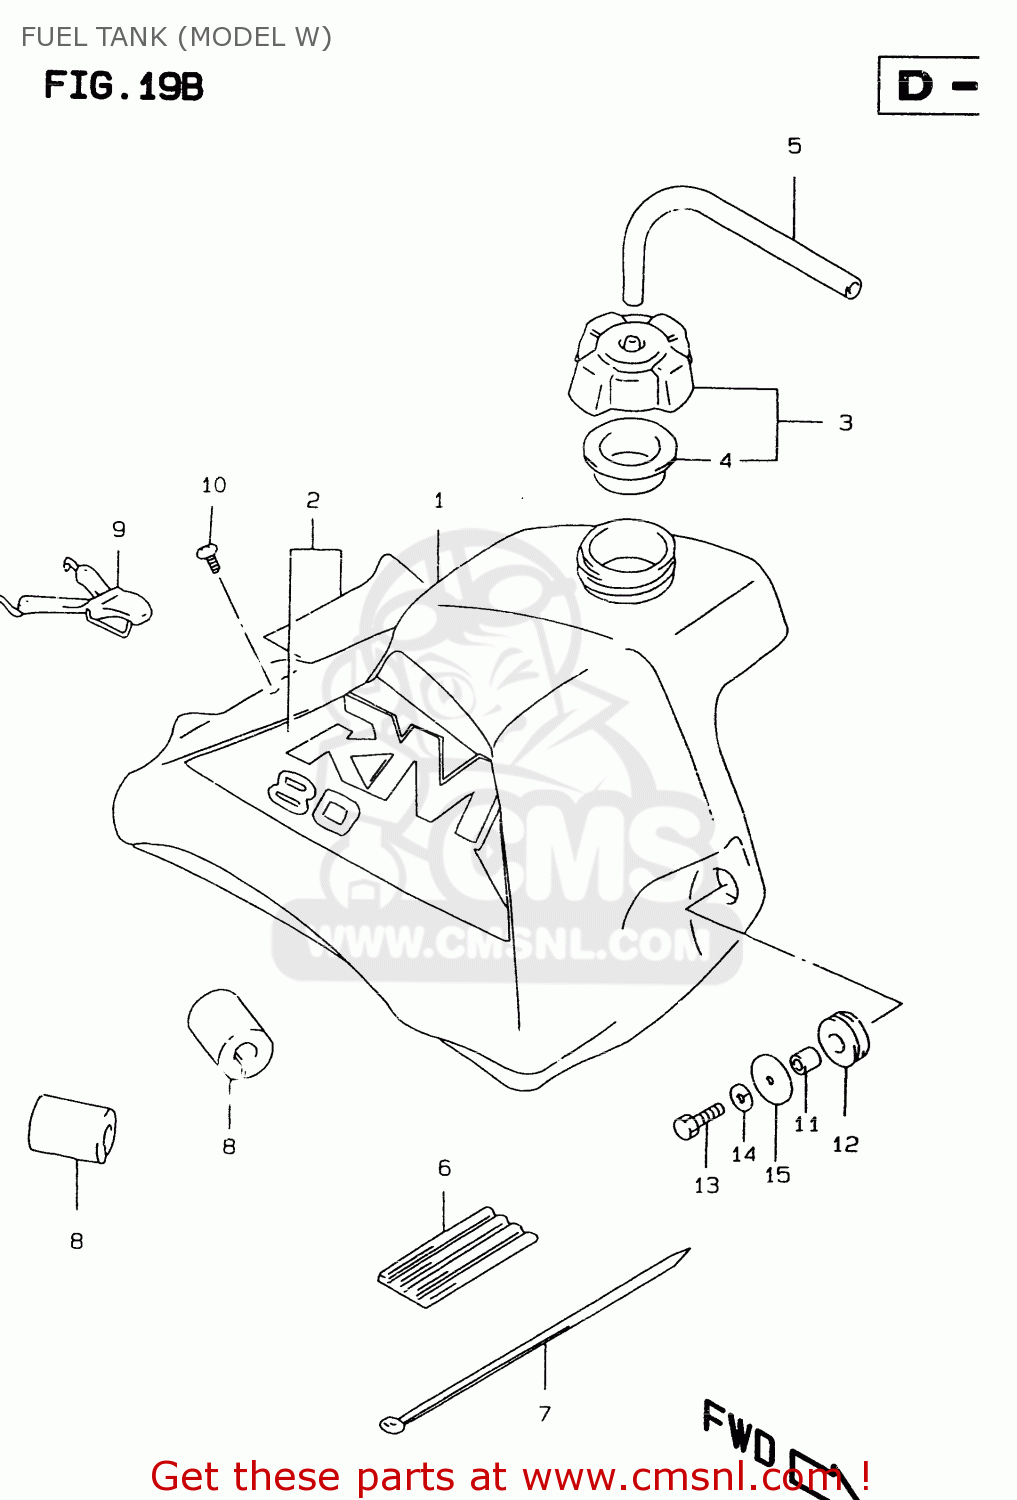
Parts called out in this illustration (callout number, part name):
1	TANK,FUEL(YELLOW)
2	TAPE SET,FUEL TANK
3	CAP SET,FUEL TANK
4	GASKET,CAP (NAS)
5	HOSE(5X8.2X600)
6	CUSHION,FUEL TANK UPR FR
7	CLAMP(L:250)
8	CUSHION,FUEL TANK UPR RR
9	BAND,FUEL TANK RR
10	SCREW
11	SPACER(6.5X10X11.5)
12	CUSHION
13	BOLT
14	LOCK WASHER
15	WASHER(6.5X24X1.6)
